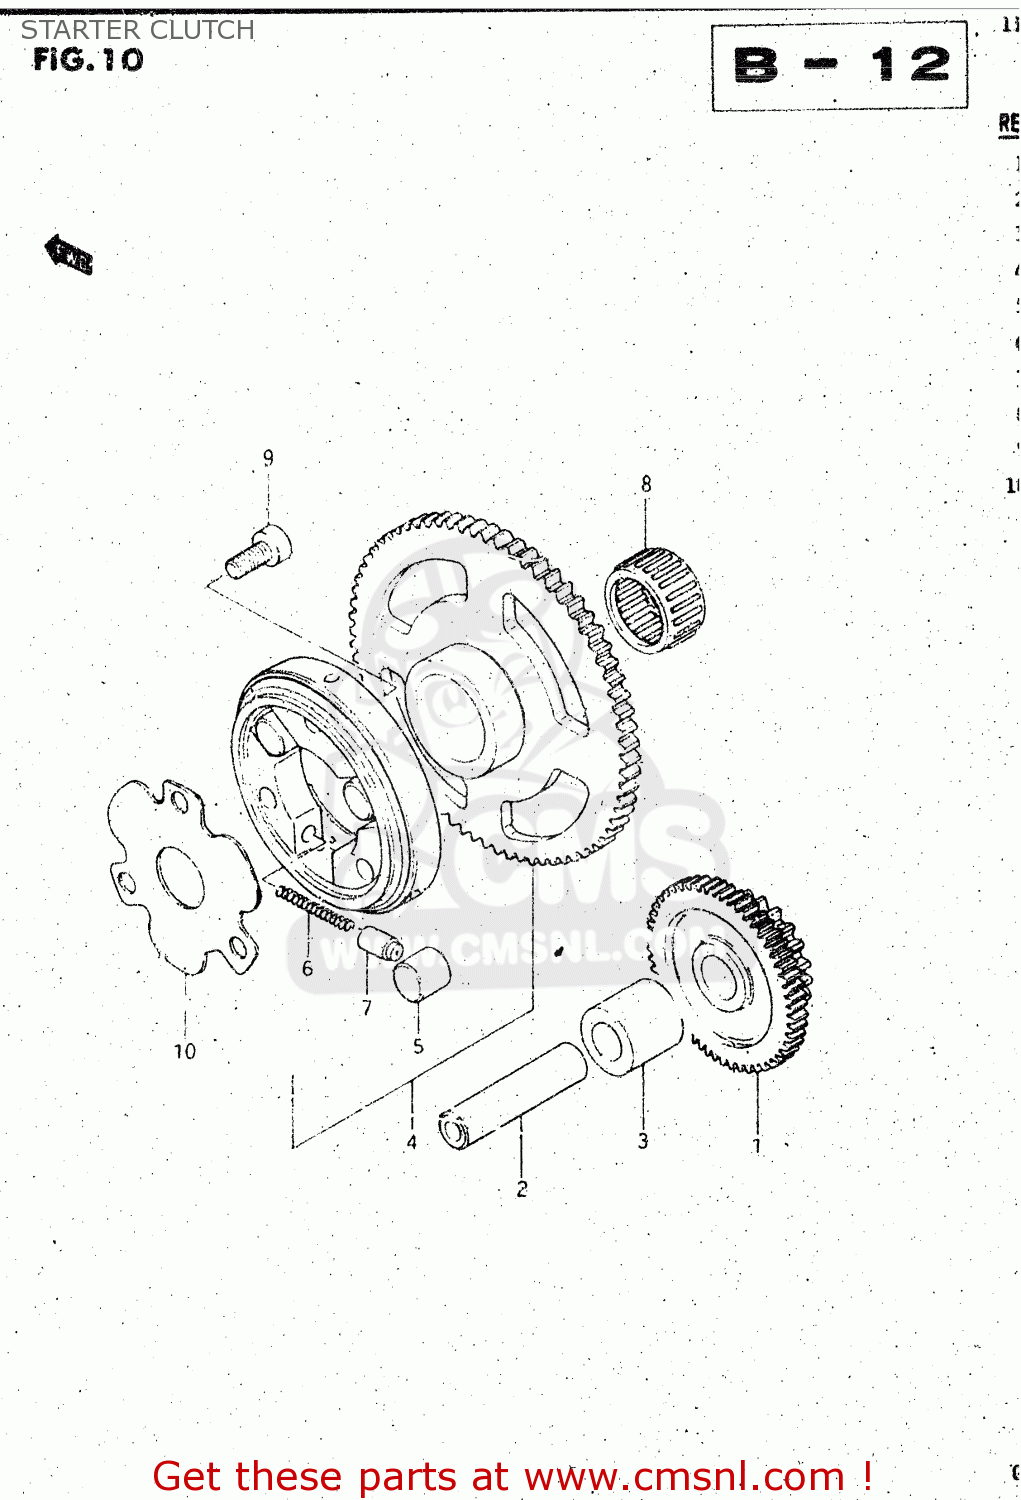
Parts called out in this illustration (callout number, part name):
1	GEAR,STARTER IDLER
2	PIN(7.4X13X56)
3	SPACER(13X19X19)
4	CLUTCH SET,STARTER
5	ROLLER(10X11)
6	SPRING
7	PIECE,STARTER CLUTCH PUSH
8	BEARING(22X28X16)
9	BOLT,OIL FILLE
10	SHIM,STARTER CLUTCH HUB
